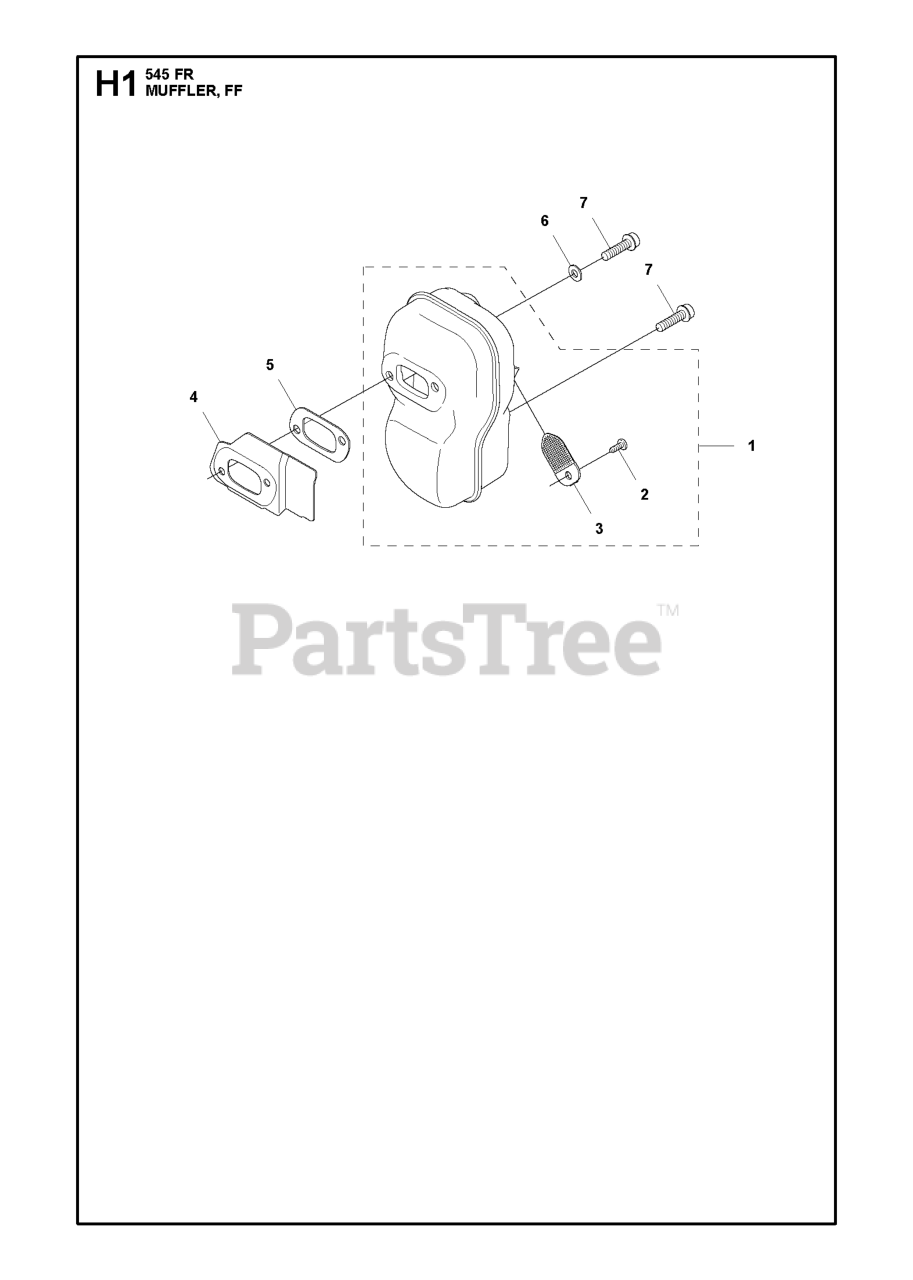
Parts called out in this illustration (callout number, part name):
1	MUFFLER KIT NEW BAFFLE
3	SPARK ARRESTOR SCREEN
4	HEAT DEFLECTOR
6	DOUBLE WASHER
